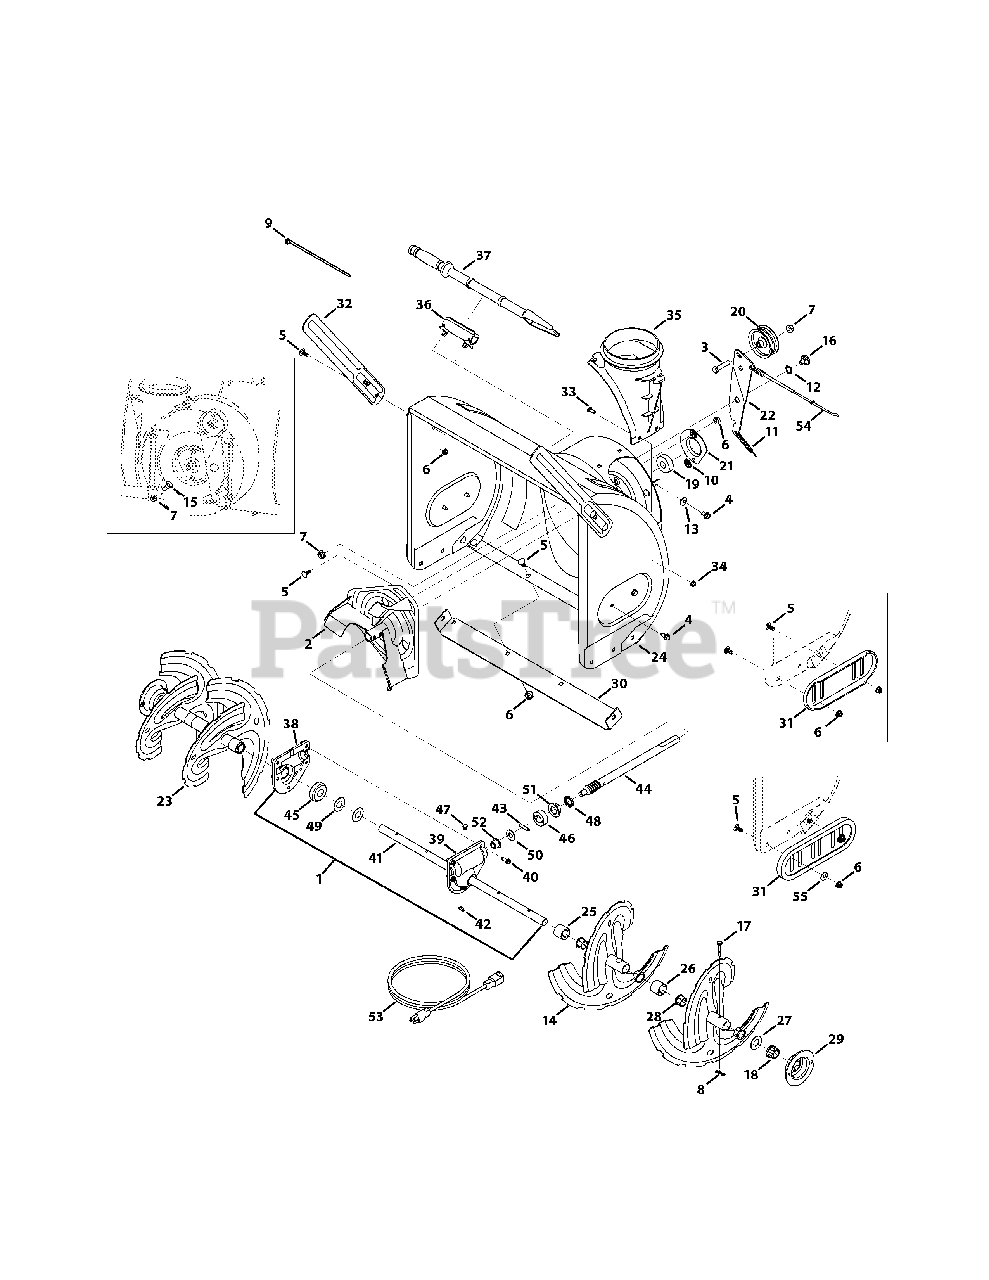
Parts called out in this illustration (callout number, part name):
1	Auger Gearbox, includes 38-52
2	Impeller Assembly, 12" Dia.
3	Hex Head Screw, 3/8-16 x 1.75
4	Screw, 5/16-18 x .750
5	Screw, Carriage, 5/16-18 x 1.00
6	Nut, Flange lock, 5/16-18
7	Nut, Flange lock, 3/8-16
8	Bow-Tie Cotter Pin
9	Cable Tie, 7"
10	Nut, Push-on, .25 Dia.
11	Extension Spring, .38 x 4.59
12	Washer, Wave, .625 x .885
13	Washer, Bell, .340 x .872
14	Spiral Assembly, LH
15	Bolt, Shoulder, .496 x .336 x 3/8-16
16	Screw, Shoulder, .625 x .17 x 3/8-16
17	Shear Pin, .25 x 1.50
18	Bearing, Hex Flange, .75
19	Bearing, Ball, .75 x 1.85
20	Pulley, Idler, Flat, 2.75
21	Bearing, 1.85 ID
22	Auger Idler Bracket
23	Spiral Assembly, RH
25	Spacer, 1.25 x .75 x 1.00
26	Spacer, 1.25 x .75 x 2.00
27	Washer, Flat, .76 x 1.49
28	Bushing, Flange, .800 x .910
29	Bearing, 1" Hex
30	Shave Plate, 2.25 x 29.66
31	Polymer Slide Shoe
31	Deluxe Polymer Reversible Shoe Kit
32	Blade Guide
33	Screw, Carriage, 1/4-20 x .75
34	Nut, Flange lock, 1/4-20
35	Chute Adapter
36	Clean-Out Tool Mount
37	Clean-Out Tool
38	Reducer, RH
39	Reducer, LH
40	Screw, 1/4-20 x 0.750
41	Auger Axle, 30"
42	Key, Hi-Pro, 3/16 x 5/8
43	Dowel Pin, .25 x 1.25
44	Worm Shaft, .75
45	Gear Worm, 20T
46	Collar Thrust, .756 x .600
47	Plug, 1/4 x .437
48	Oil Seal, .75 x 1.131 x .188
49	Washer, Flat, .760 x 1.50
50	Washer, Flat, .51 x 1.12
51	Bearing, Flange, .75 x 1.00 x .59
52	Bearing, Flange, .50 x .75 x .59
53	Extension Cord, 110V
54	Auger Drive Clutch Cable
55	Washer, Flat, .349 x .879 x .063
